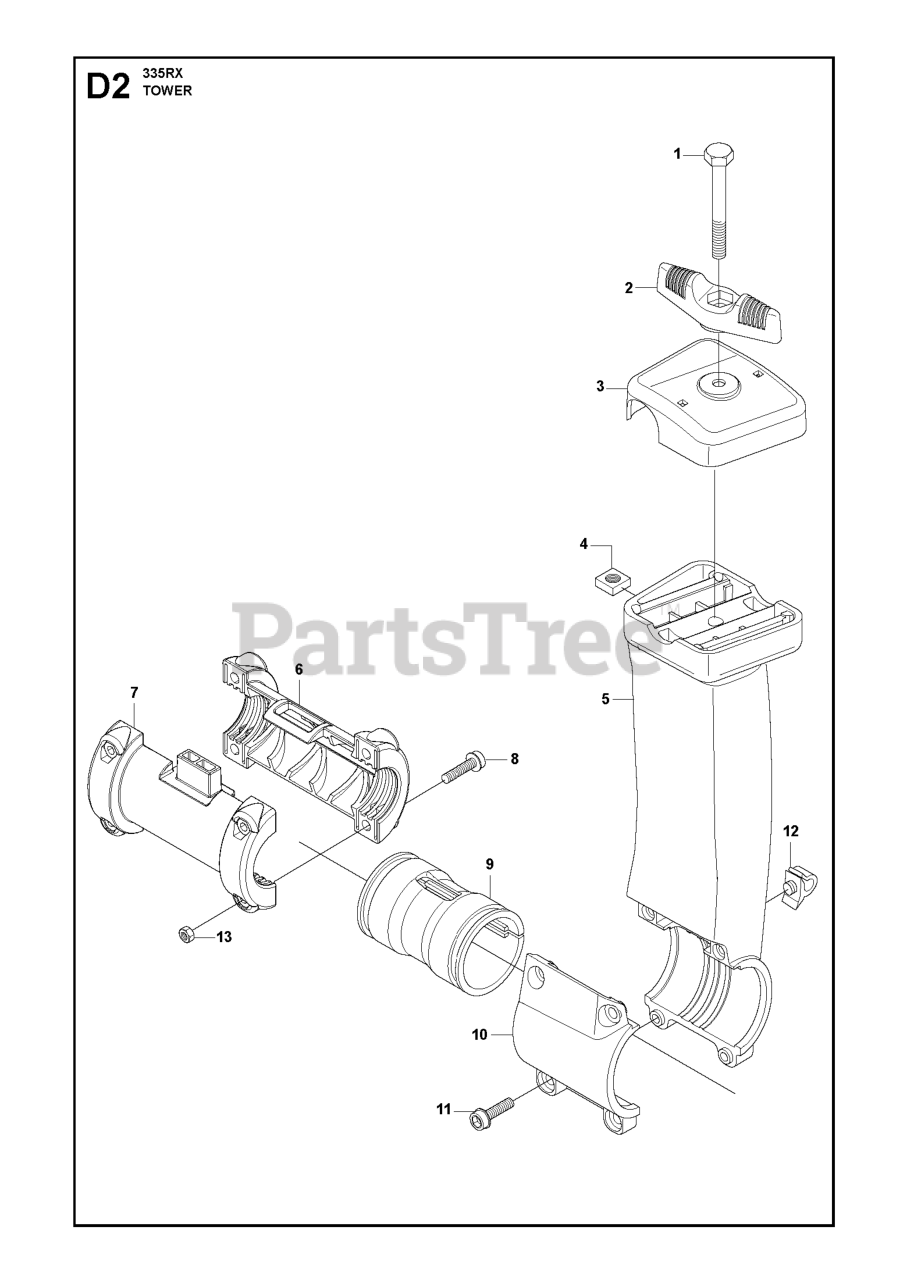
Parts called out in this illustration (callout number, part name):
1	%SCREW
3	PROTECTOR CLAMP
5	BRACKET
6	CLAMPING SLEEVE
7	CLAMPING SLEEVE ASSY
9	VIBRATIONS ABSORBER
10	COVER, BRACKET
